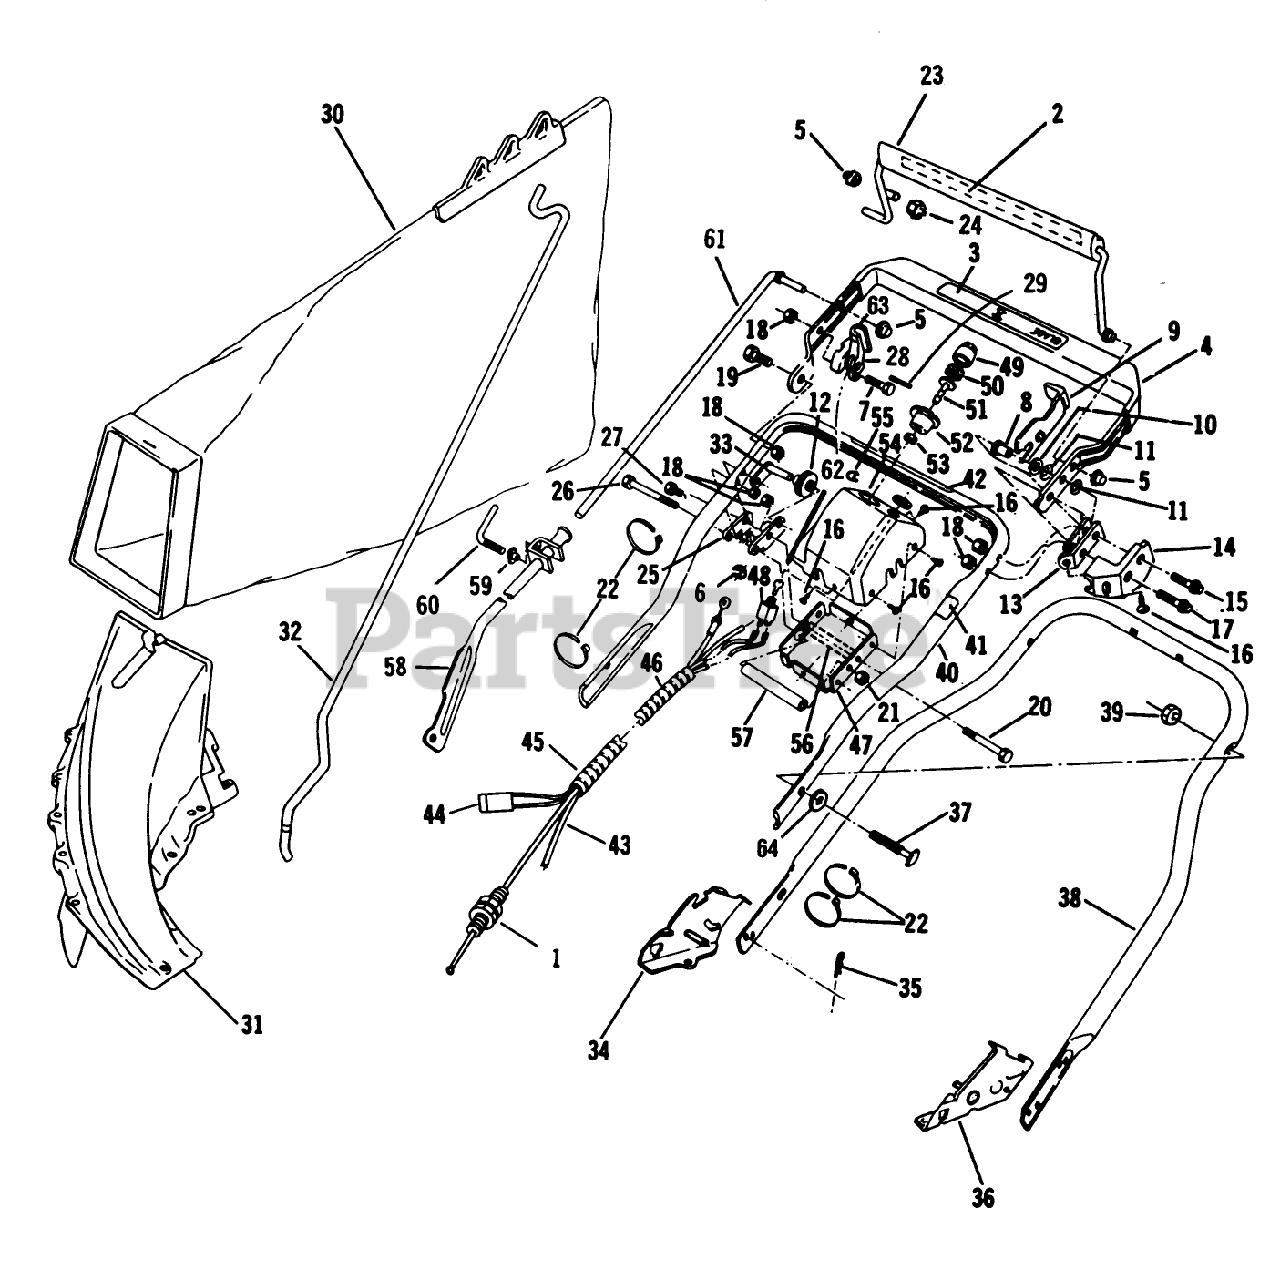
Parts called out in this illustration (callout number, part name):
1	CONTROL CABLE
6	RET. RING
8	SPACER
10	WASHER M
13	DOWN STOP
14	LOCKOUT GUARD
15	BOLT SHOU
16	SCREW F
17	SCREW
18	LOCKNUT E
19	BOLT
24	NUT ACORN
26	BOLT-CONSOLE
30	89802 LB WHOLE GOODS
32	ROD GRASSBAG
34	BRACKET ASM - HANDLE, SP, RH
35	HAIR PIN
36	BRACKET ASM - HANDLE, SP, LH
37	WHOLE GOODS PART
39	NUT-LOCK F
50	FILTER S
53	LOCKNUT S
56	SPACER
61	CONTROL ROD
64	WASHER-CURVED
